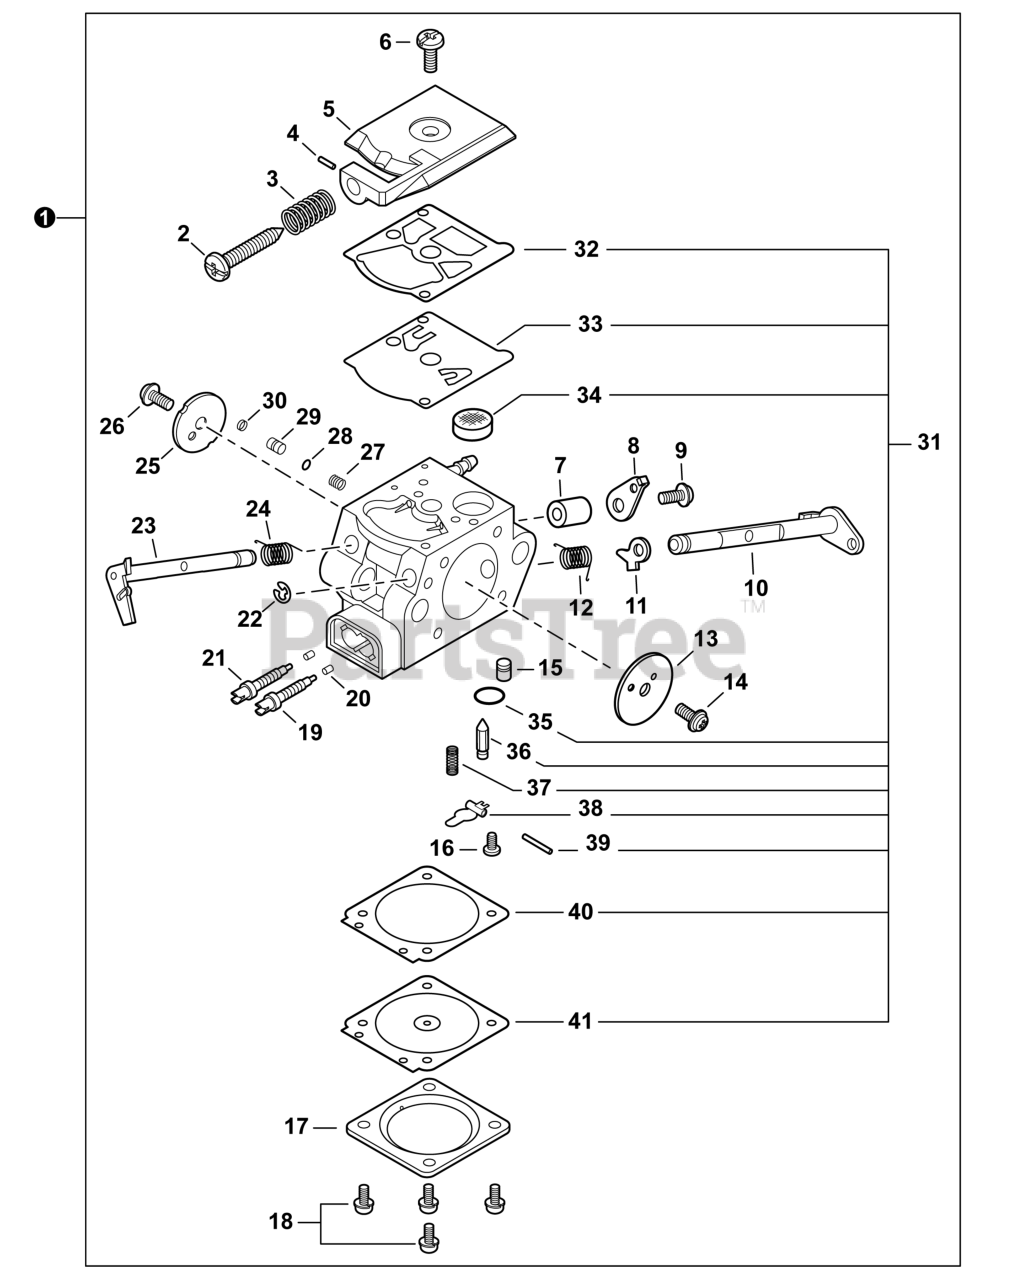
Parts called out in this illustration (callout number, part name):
1	CARBURETOR C1Q-110124A
4	PIECE, FRICTION
5	COVER, PUMP
8	LEVER, THROTTLE
10	SHAFT, CHOKE
11	LEVER, CHOKE
12	SPRING, CHOKE RETURN
13	VALVE, CHOKE
14	SCREW 3×4.5
15	NOZZLE, CHECK VALVE
17	COVER, METERING DIAPHRAGM
19	NEEDLE, HIGH SPEED
20	RETAINER
21	NEEDLE, IDLE
23	SHAFT, THROTTLE
25	VALVE, THROTTLE
29	PLUNGER
31	REPAIR KIT
32	GASKET, PUMP
33	DIAPHRAGM, PUMP
34	SCREEN, FUEL INLET
35	PLUG, WELCH
36	VALVE, INLET NEEDLE
37	SPRING, COIL
38	LEVER, METERING
39	PIN, METERING LEVER
40	GASKET, METERING DIAPHRAGM
41	DIAPHRAGM, METERING
